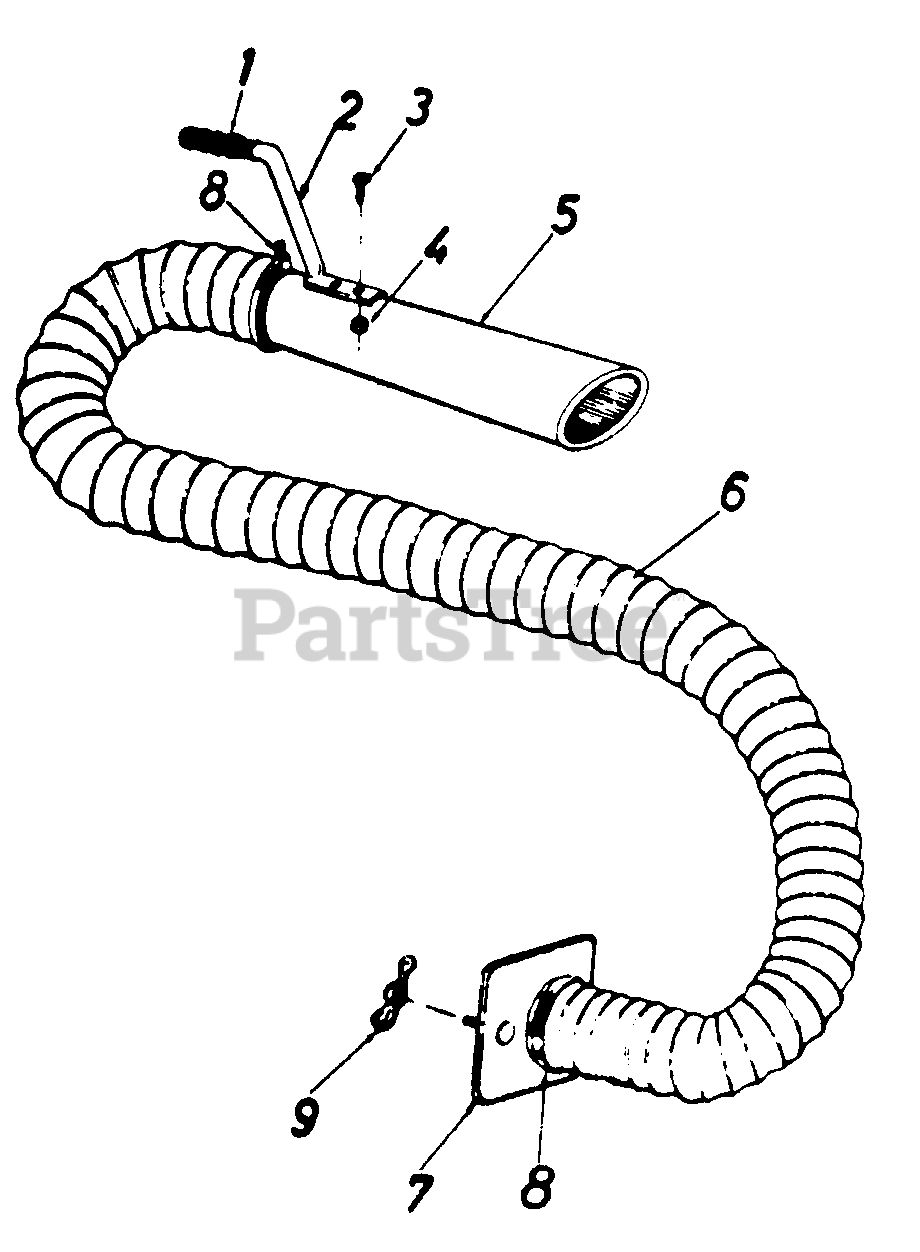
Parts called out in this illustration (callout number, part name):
1	Handle Grip
2	Handle
3	Truss Sems Scr. 10-24 x 1/2" Lg.
4	Hex Nut 10-24 Thd.
5	Hose Nozzle
6	Flexible Hose 4" Dia. x 10' Lg.
7	Hose Adapter Plate
8	Hose Clamp - For 4" Dia. Hose
9	Wing Nut 1/4-20 Thd.
